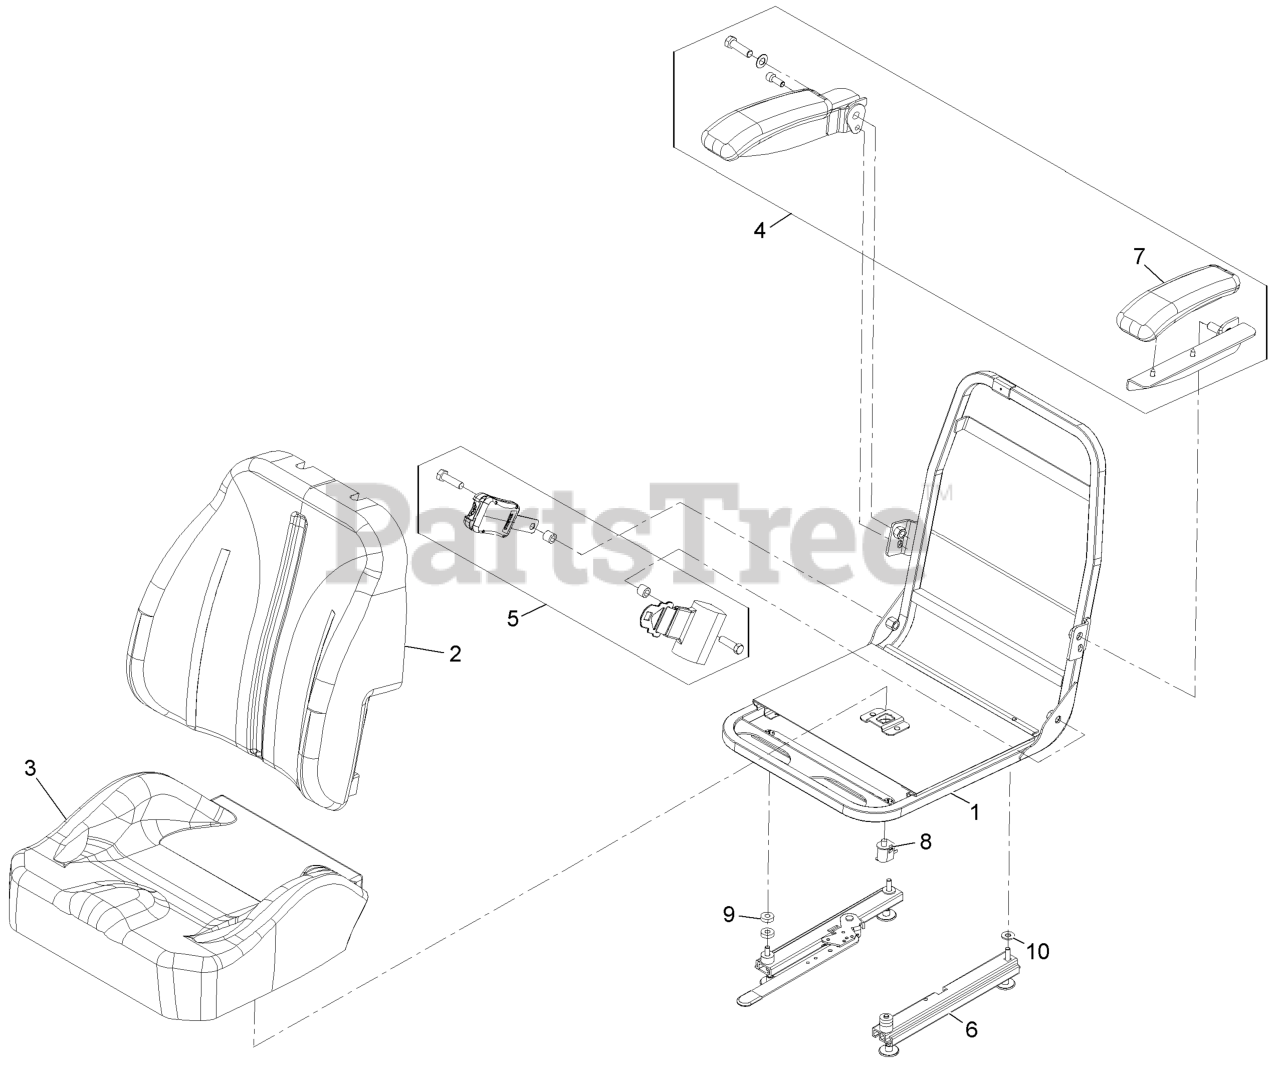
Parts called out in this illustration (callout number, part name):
1	Asm-Seat Lze
2	COVER-SEAT BACK
3	COVER-SEAT CUSHION
4	ARMREST KIT
5	SEAT BELT SERVICE KIT
6	TRACK-SEAT
7	CUSHION-REST, ARM
8	SWITCH-BAIL
10	WASHER-FLAT
